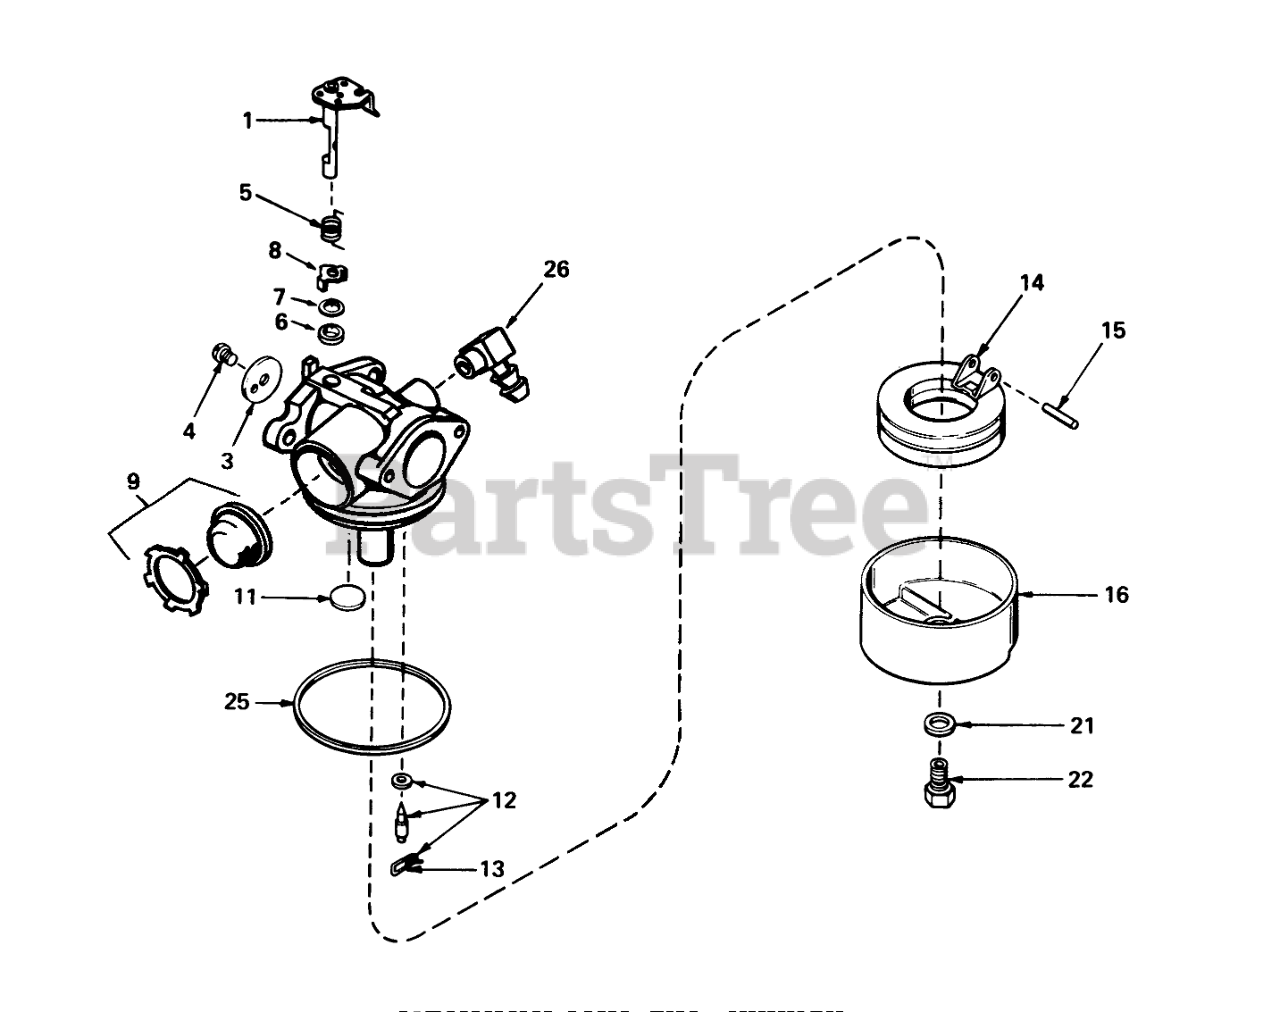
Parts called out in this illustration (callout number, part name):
1	Throttle Shaft and Lever ASM
3	Throttle-Shutter
4	Screw-Shutter
5	Spring, Return
6	Seal-Dust
7	Washer-Seal, Dust
8	Retainer, Seal
9	Primer Assy.
11	Plug-Welch, Atmospheric Vent
12	Inlet Needle, Seat & Clip Assembly (Incl. Ref. #13)
13	Clip-Spring
14	Float
15	Shaft-Float
16	Bowl Float
21	Gasket-Bowl
22	Nut, Float Bowl
25	O Ring-Bowl, Float
26	Fitting-Fuel
